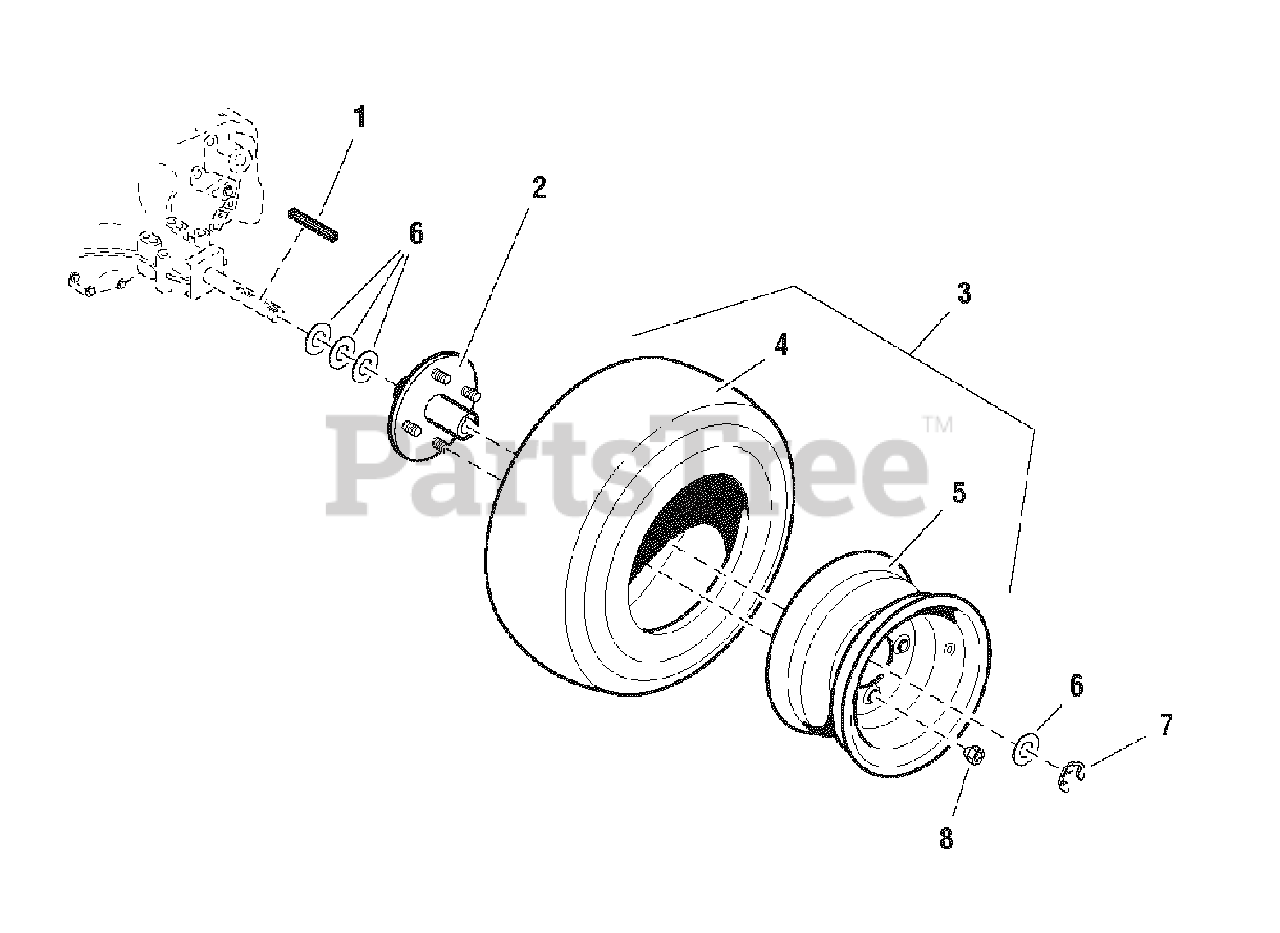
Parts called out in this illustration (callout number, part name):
1	KEY, 3/16
2	DRIVE HUB
4	TIRE, 16. x 6.5 x 8
5	WHEEL ASSEMBLY, 8 x 5.38
6	SHIM
7	C-CLIP
8	LUG NUT
